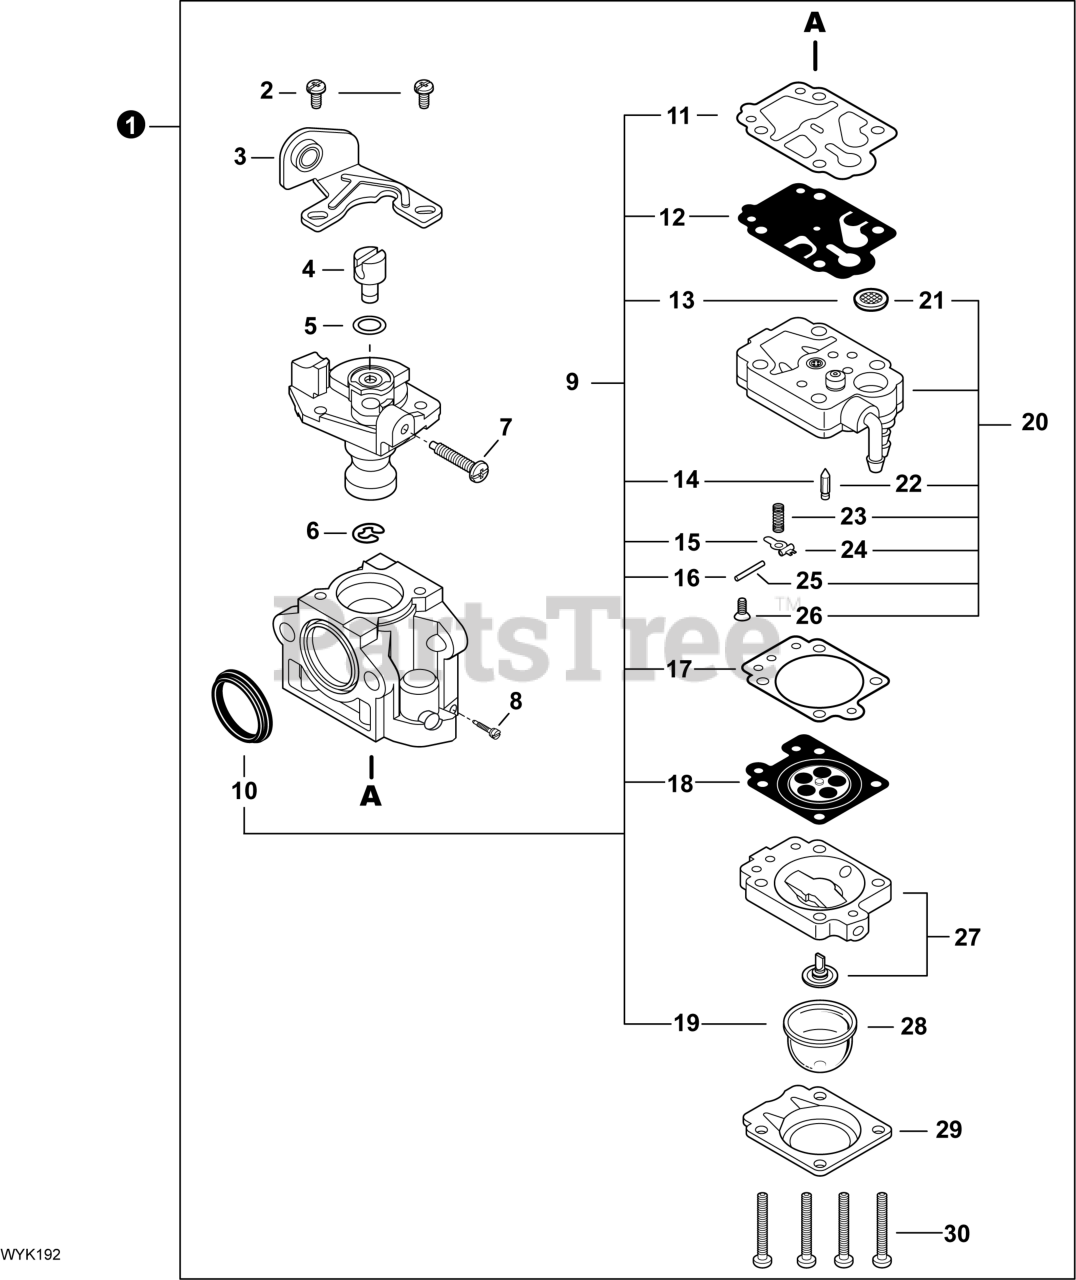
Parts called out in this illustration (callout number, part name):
1	CARBURETOR, PB-755
2	SCREW
3	BRACKET, THROTTLE CABLE
4	SWIVEL
5	WASHER
6	E-RING
7	SCREW
8	NEEDLE, HIGH SPEED
9	REPAIR KIT, CARBURETOR
10	RING, PACKING
11	GASKET, PUMP
12	DIAPHRAGM, FUEL PUMP
13	SCREEN, FUEL INLET
14	VALVE, INLET NEEDLE
15	LEVER, METERING
16	PIN, METERING LEVER
17	GASKET, METERING DIAPHRAGM
18	DIAPHRAGM, METERING
19	BULB, PURGE
20	BODY ASSY, PUMP
21	SCREEN, FUEL INLET
22	VALVE, INLET NEEDLE
23	SPRING, METERING LEVER
24	LEVER, METERING
25	PIN, METERING LEVER
26	SCREW
27	BODY ASSY, PURGE
28	BULB, PURGE
29	RETAINER, PURGE BULB
30	SCREW
